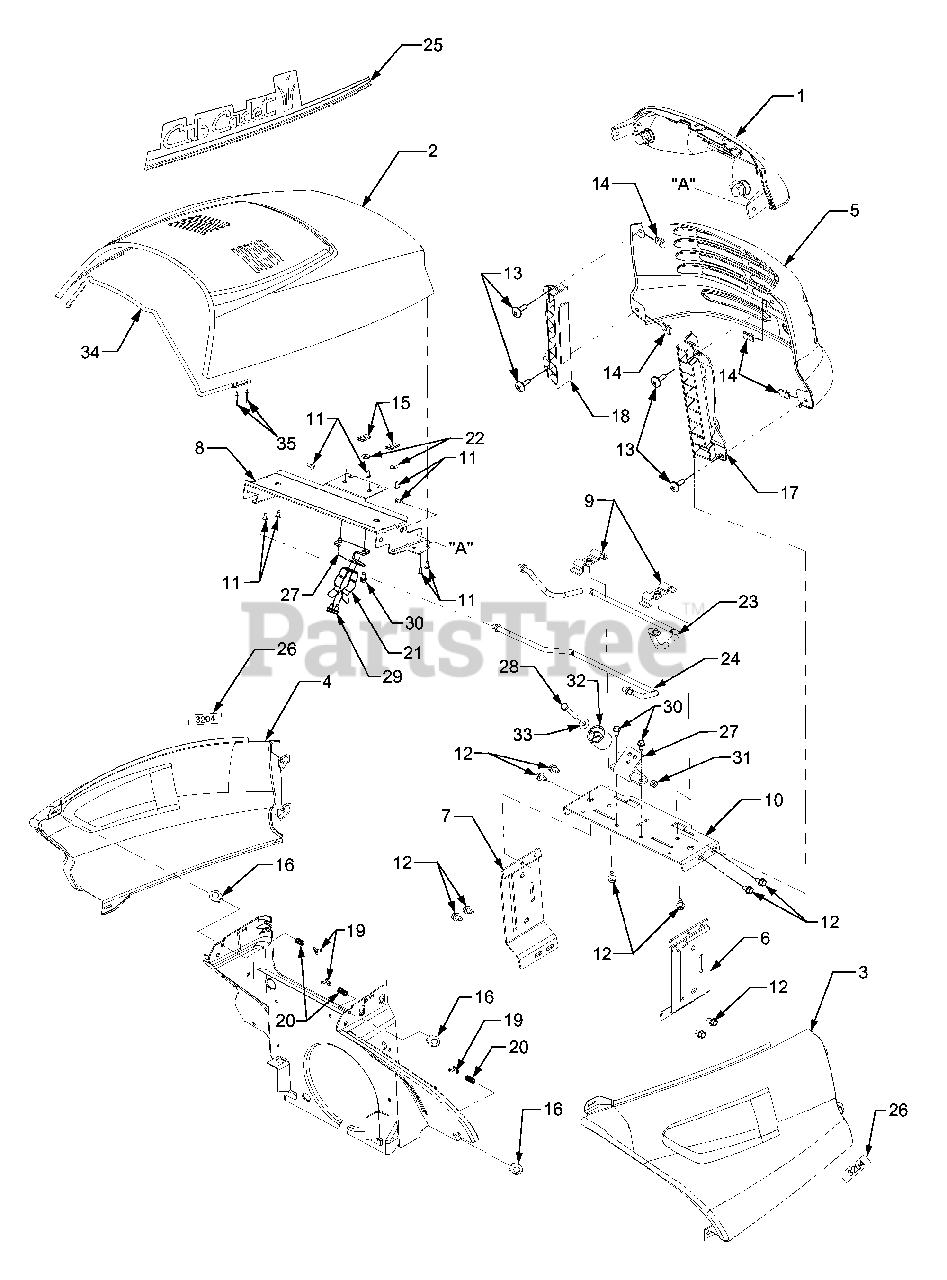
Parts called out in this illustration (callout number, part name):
1	Headlight Assembly
3	Side Panel, RH
4	Side Panel, LH
5	Grille, Series 3000
6	Support, Grille - RH
7	Support, Grille - LH
8	Bracket, Upper Hood
9	Bracket, Rod Retainer
10	Support, Hood
11	Screw, Truss Hd, Tapp, #10-16 x .5
12	Screw, Hex Wash. Hd. Tapp 5/16-18 x .5
13	Screw, Phil. Pan Hd. 1/4-20 x .75
14	Nut, U Type Speed, 1/4-20
15	Nut, U-type Speed, #10
16	Latch, 1/4 Turn
17	Mount, Side Panel/Grille RH
18	Mount, Side Panel/Grille LH
19	Clip, Spring
20	Spring, Compression
21	Spring, Hood Latch
22	Washer, Flat, .194 x .62 x .063
23	Rod, Upper Hood
24	Rod, Lower Hood
25	Graphic, Hood - RH
26	Baffle, Lower Air
27	Bracket, Hood Latch Support
28	Screw, Hex Cap, 1/4-20 x 1.75 GR5
29	Screw, Hex Wash Hd Tapp, 1/4-20 x .5
30	Screw, Hex Wash Hd Tapp, 1/4-14 x .5
31	Nut, Hex Top Lock, 1/4-20
32	Roller, Hood Latch
33	Washer, Flat, .283 x .75 x .030
34	Rod, Hood Support
35	Rivet, Pop, .125 OD
